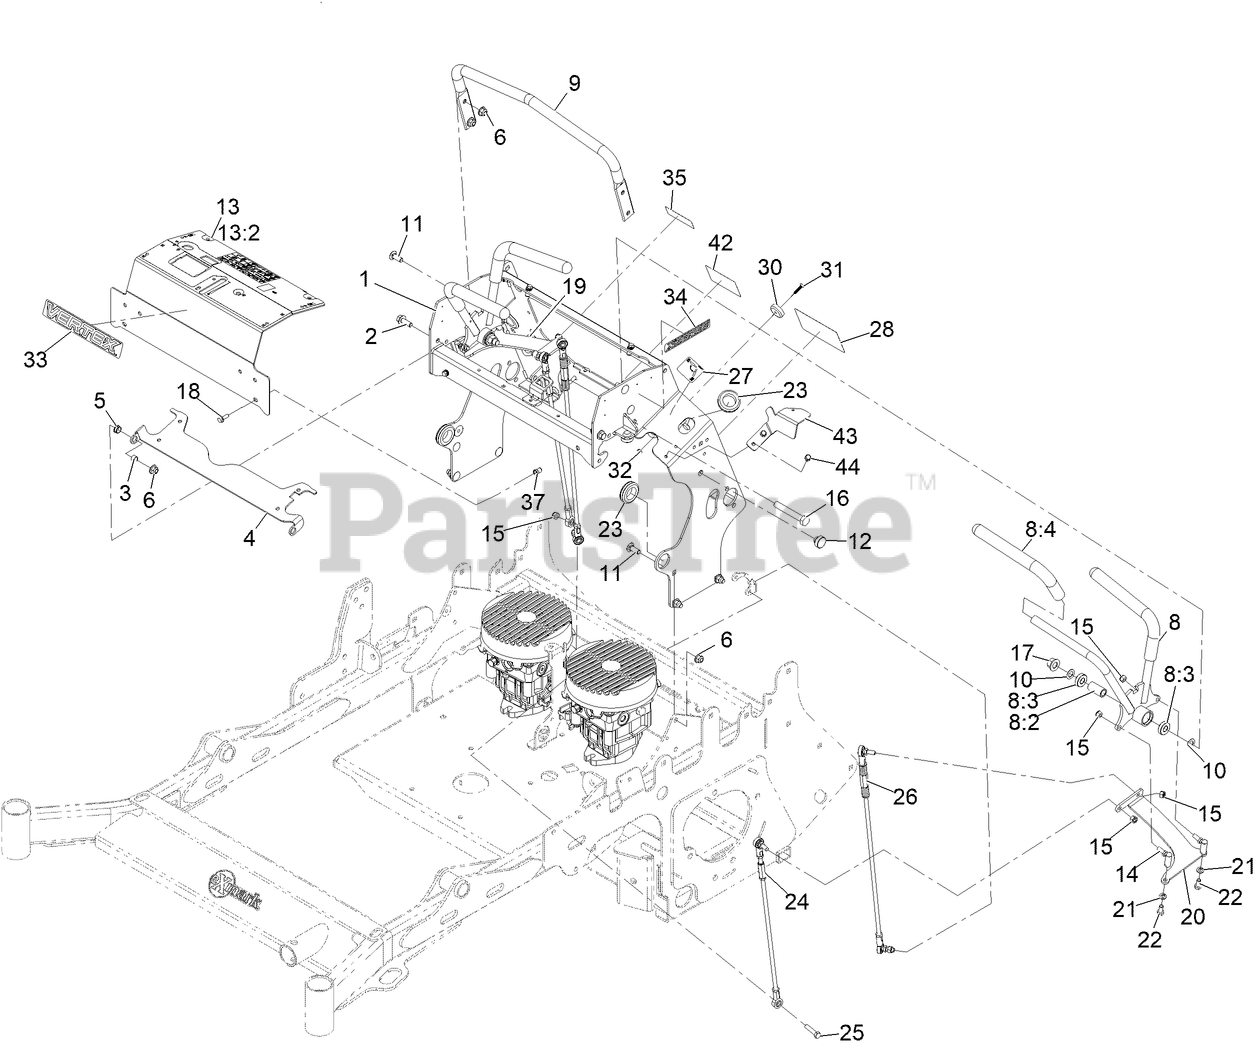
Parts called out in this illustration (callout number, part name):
1	ASM-TOWER
2	SCREW-HHF 3/8-16 X 1
3	SPACER-BRAKE PIVOT
4	PLATE-MOTION CNTRL LOCK
5	BUSHING,SNAP
6	NUT-HF, NI
8	ASM-CTRL LEVER
8:3	BEARING-WHEEL
8:4	GRIP-HANDLE, CONTROL
9	BAR-REFERENCE
11	SCREW-CARR
12	BUMPER-RUBBER
13	ASM-CONTROL PANEL W/DCL
13:2	DECAL-CONTROL PANEL
14	BALLJOINT-RH (W/GROMMET)
15	NUT-LOCK
16	SCREW-HH
17	Nut-Lock 1/2-13
18	SCREW-HHF
19	BRACKET-LINK CTRL LH
20	BRACKET-LINK CTRL RH
21	WASHER-LOCK
22	SCREW-HH
23	GROMMET
24	ASM-MOTION CONTROL SHORT
25	SCREW-HH
26	ASM-MOTION CONTROL LONG
27	DECAL-PARK BRAKE, CE
28	DECAL-SERVICE AID
30	MAGNET-RARE EARTH THIGH PAD
31	SCREW FLAT HD #10-24X1.00
32	NUT-LOCK
33	DECAL-VERTEX LOGO
34	DECAL-X-SERIES
35	DECAL-FUSE
37	Nut-Clinch, Hex
42	DECAL-DRIVE RELEASE
43	BRACKET-FUEL LINE CLAMP LH
44	SCREW-HWH
